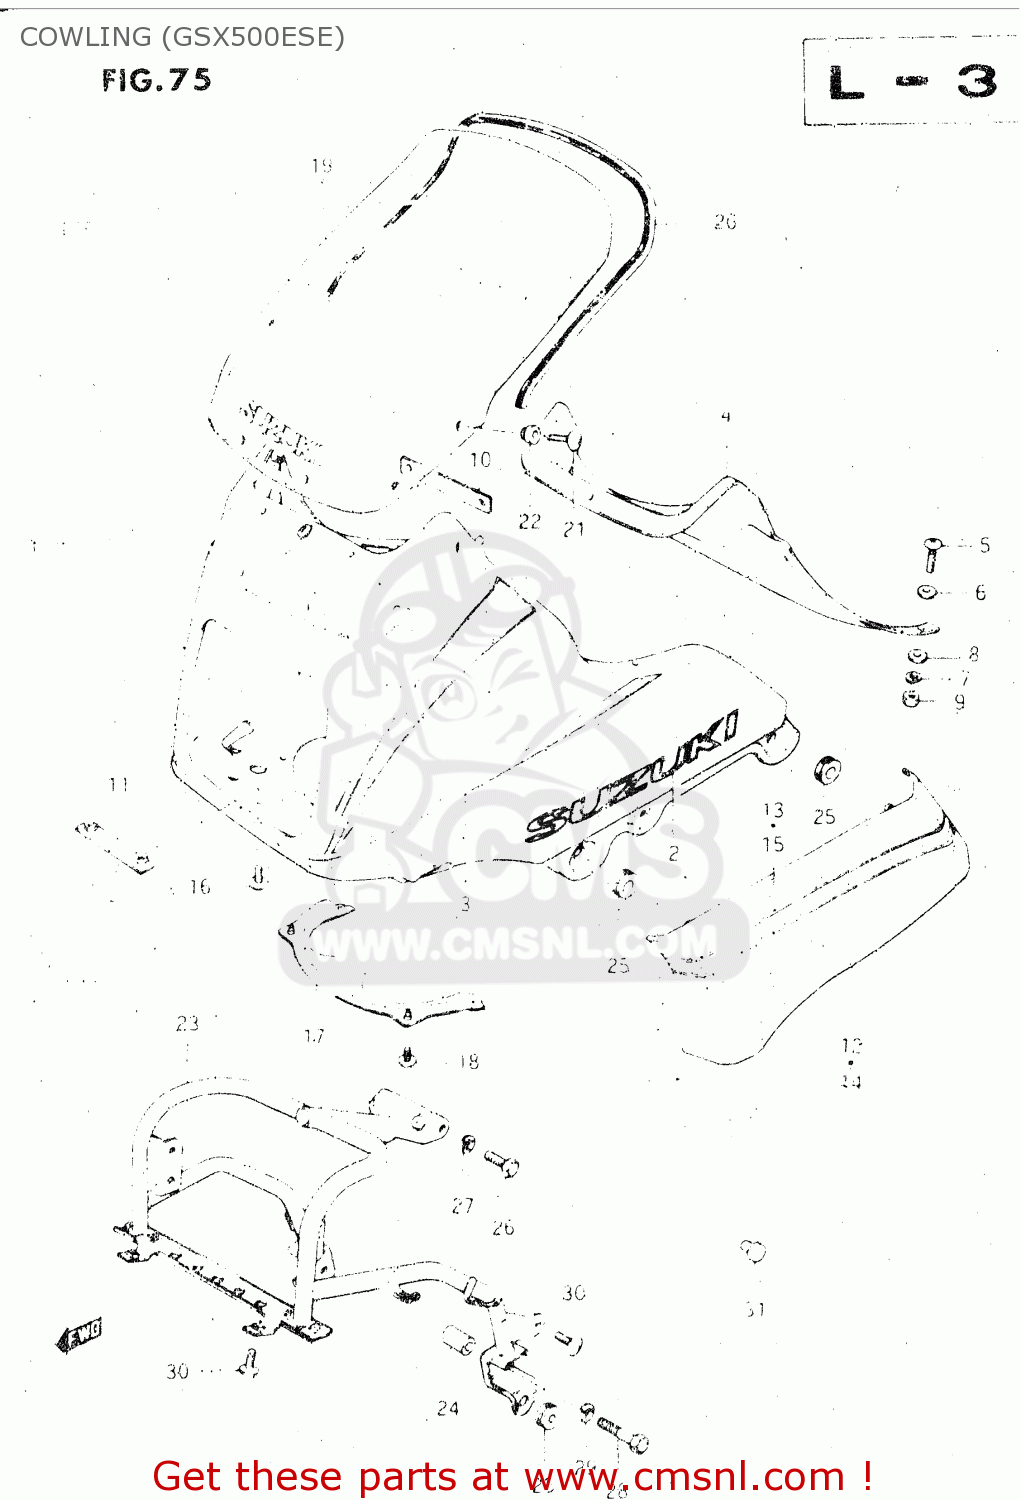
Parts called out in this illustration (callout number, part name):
1	COWLING ASSEMBLY
2	EMBLEM
3	TAPE SET
4	PANEL,COWLING,UPPER
5	SCREW
6	WASHER,5MM
7	WASHER,LOCK
8	WASHER,5MM
9	NUT ,5MM
10	BRACKET,COWLING,UPPER
11	BRACKET,COWLING,LOWER
12	COVER,COWLING,RIGHT
13	TAPE SET
14	COVER,COWLING,LEFT
15	TAPE SET
16	SCREW
17	COVER,COWLING,LOWER
18	SCREW
19	WINDOW
20	MOLDING,LOWER
21	SCREW
22	CUSHION
23	BRACE,COWLING
24	SPACER (8.2X12.5X23.5)
25	CUSHION
26	BOLT
27	LOCK WASHER
28	BOLT
29	LOCK WASHER
30	SCREW 6X12
31	PLUG
